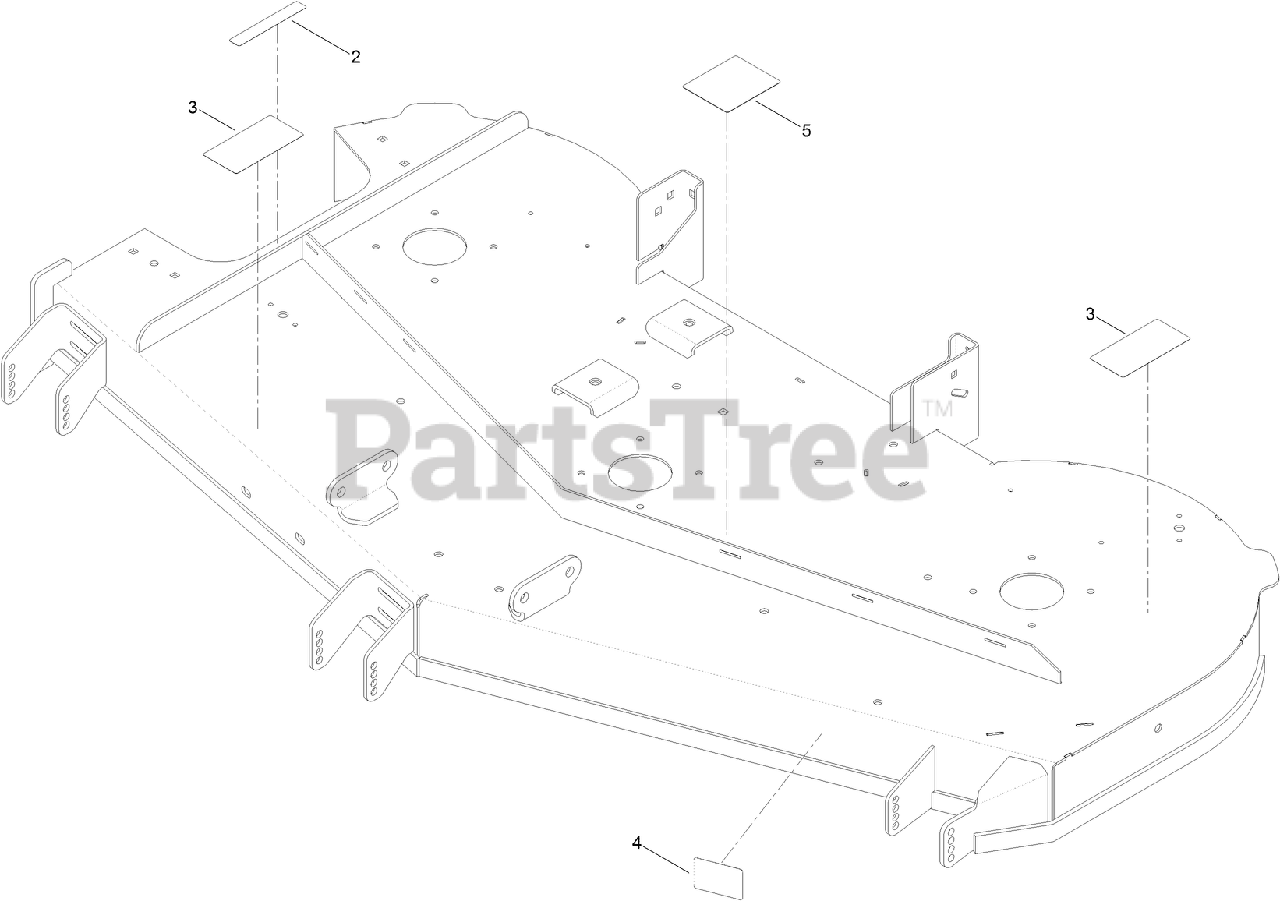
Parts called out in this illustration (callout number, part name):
2	DECAL-DANGER
3	DECAL-DANGER, DECK
4	DECAL-SCALP, ANTI
5	DECAL-ROUTING, BELT
